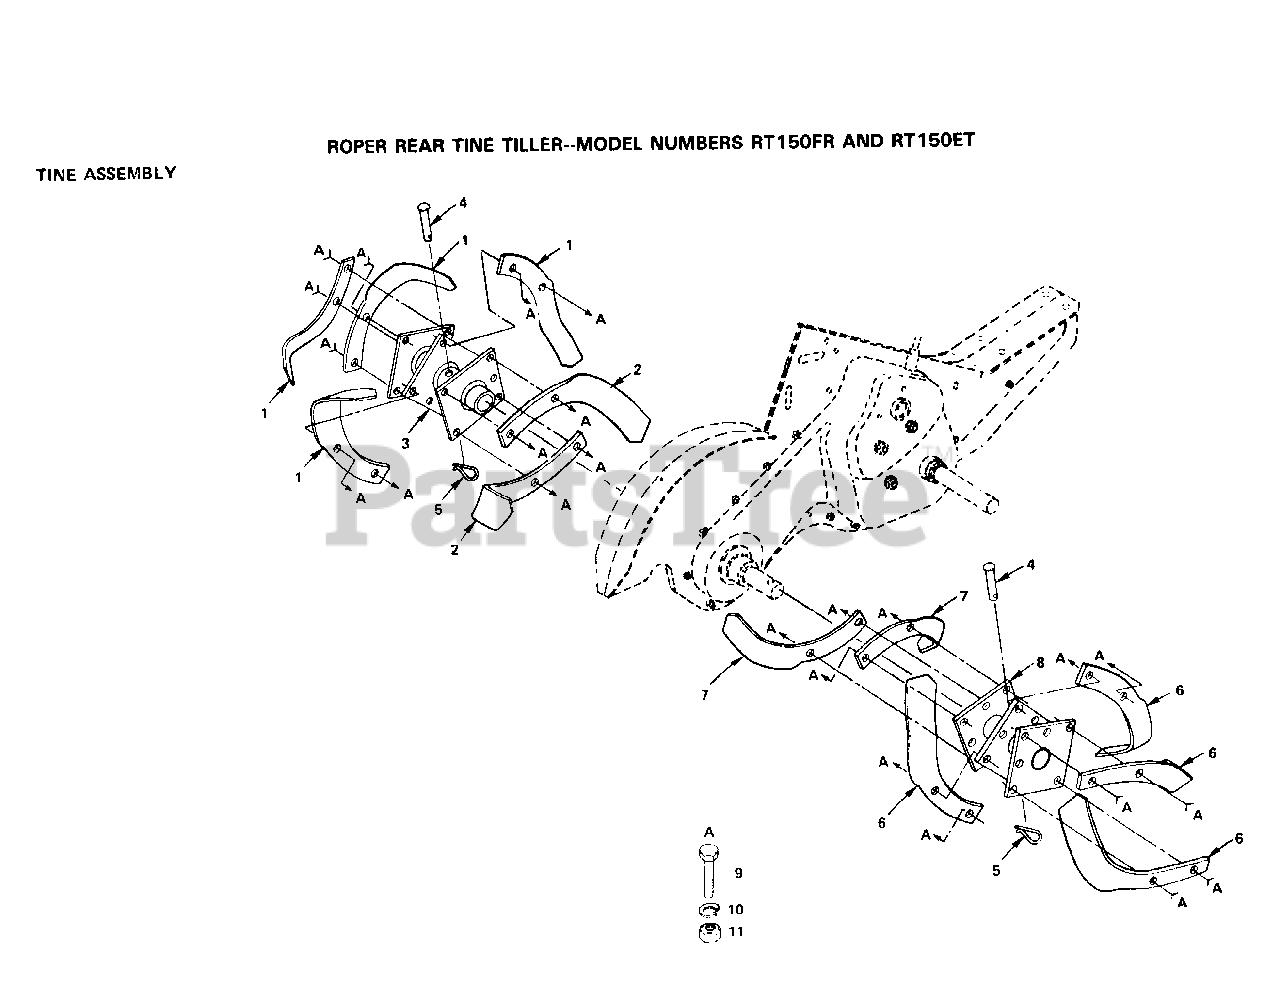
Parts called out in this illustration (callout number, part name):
2	"TINE.LH.12"""
3	TINE ASSY LH CRT
4	RIVET.PAN HD.1.75
5	RETAINER.SPRING
7	"TINE.RH.12"""
8	TINE ASSY RH CRT
9	BOLT
10	LOCKWASHER
